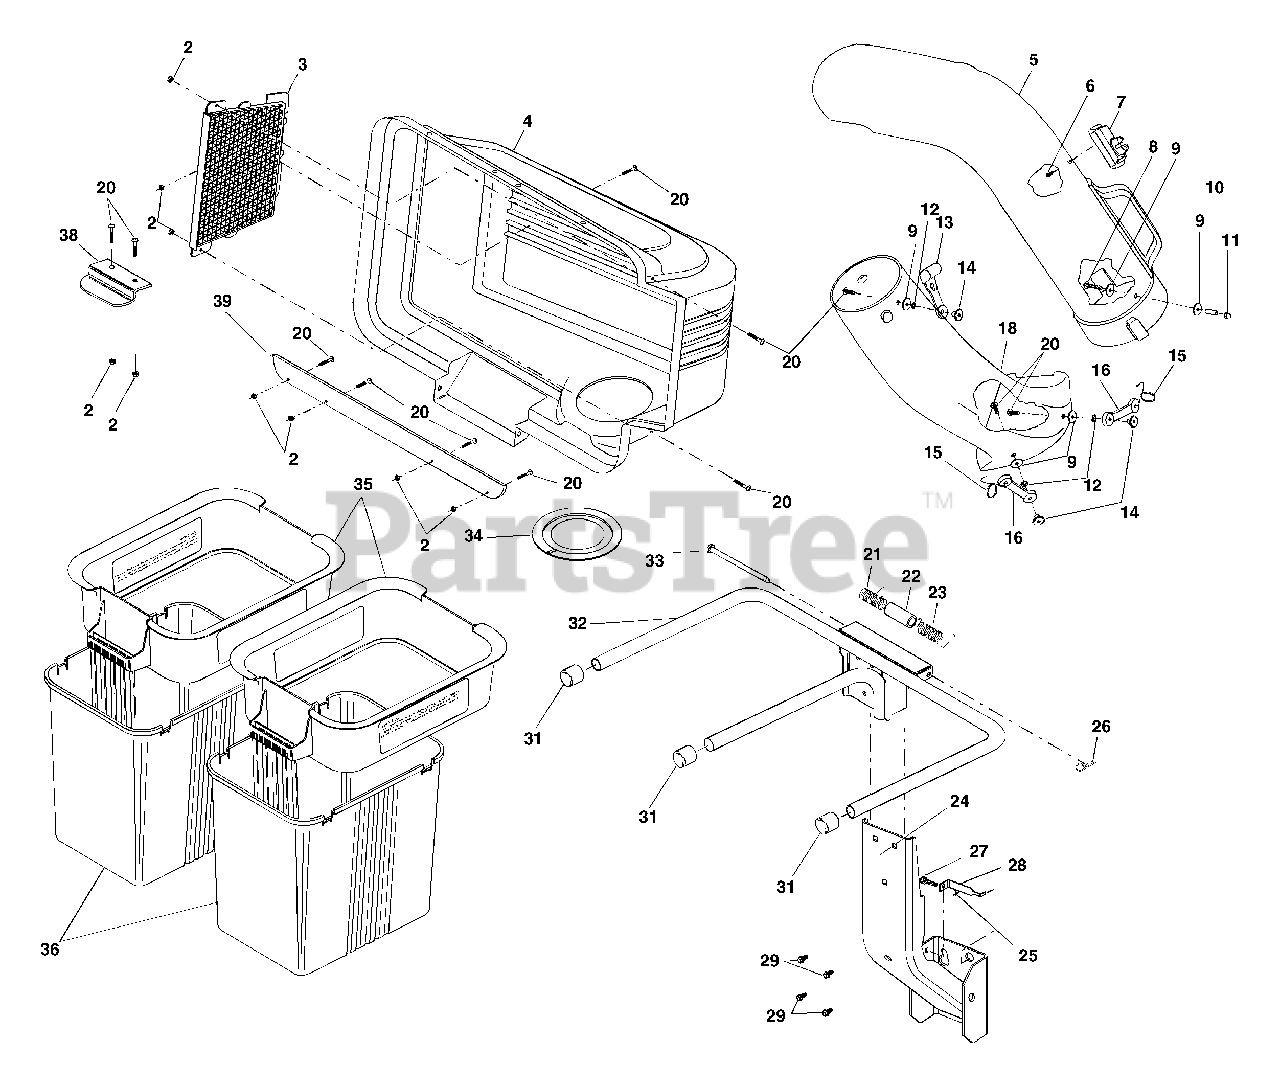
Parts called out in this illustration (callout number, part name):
2	Nut, Crownlock #10-24
3	Screen, Cover
4	Cover Assembly
6	Screw, Special #10-14x1/2
7	Dump Bag Indicator
8	Screw, #10-24 x 1-1/8
9	Washer 3/16x3/4x16 Ga.
10	Spacer, Split
11	Nut, Acorn #10-24
14	Nut, Weld
15	Latch, Hook
16	Rubber, Latch
18	Chute, Lower
20	Screw #10-24 x 5/8
21	Spring, Cover L.H. (black)
22	Spacer, Cover
23	Spring, Cover R.H. (gray)
24	Support Assembly
25	Locknut
26	Spring, Retainer
28	Bracket, Lock
29	Shoulder Bolt
31	Plug, Tubing End
32	Bagger, Frame
33	Pin, Hinge
34	Gasket, Cover
35	Container, Top
36	Container, Bottom
38	Latch Handle, Cover
39	Strip, Reinforcement
